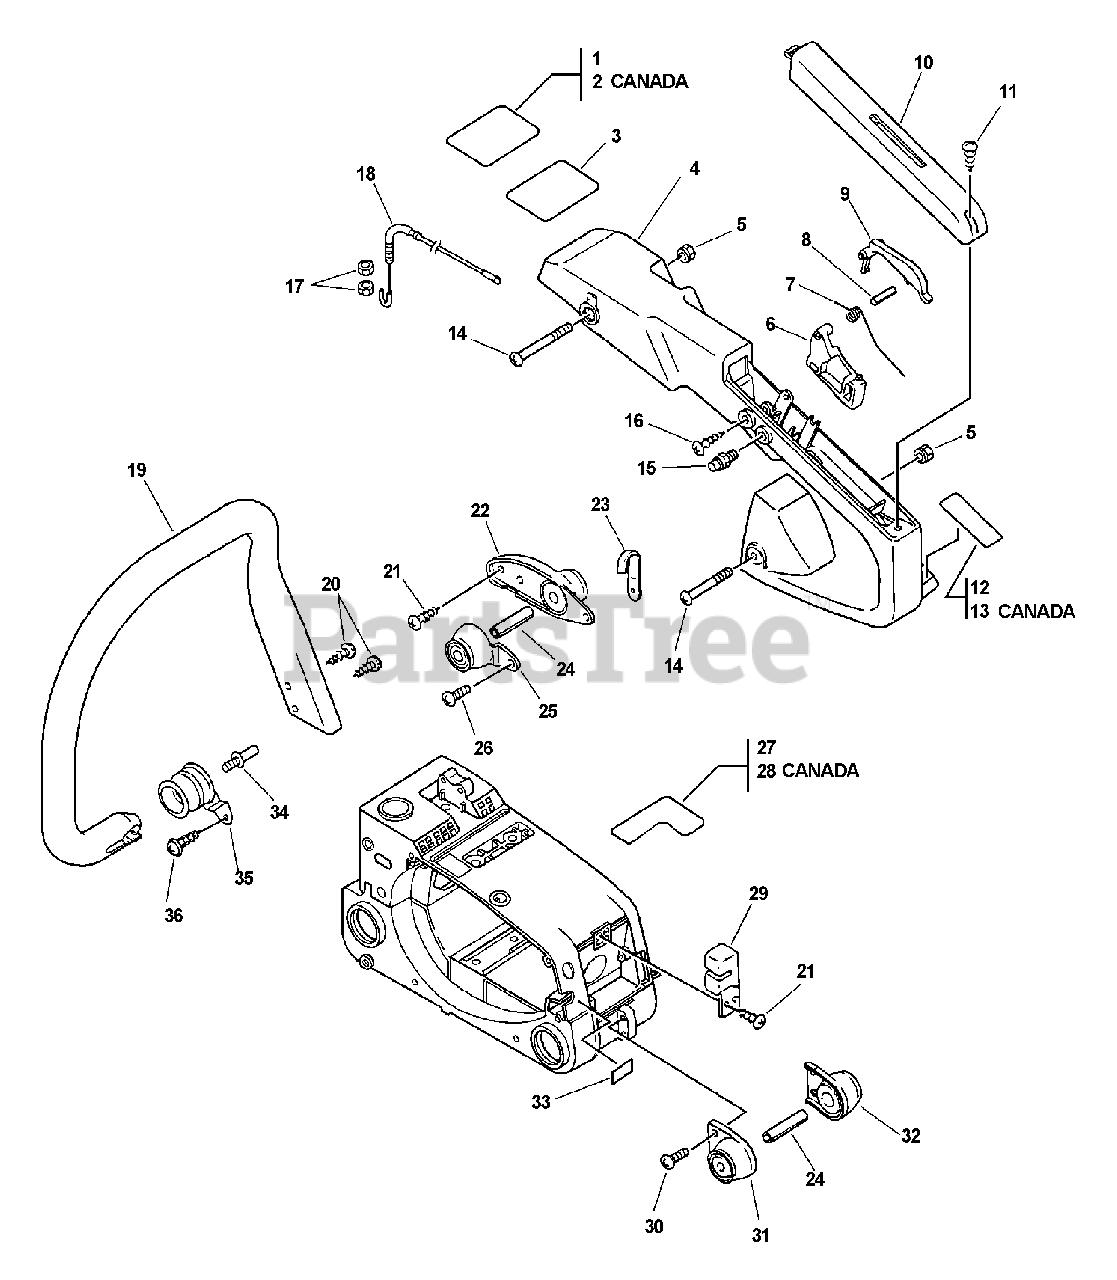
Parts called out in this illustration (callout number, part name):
1	LABEL, UL - KICK BACK
2	LABEL, CAUTION
3	LABEL, NOISE - ENGLISH/FRENCH
4	HANDLE, REAR
5	NUT, FLANGE M5
6	CONTROL, THROTTLE
7	SPRING, THROTTLE LOCKOUT
8	ROLLER, 4×19.8
9	LOCKOUT, THROTTLE
10	COVER, HANDLE
11	SCREW 4×22
12	LABEL, CAUTION
13	LABEL, ATTENTION - CANADA
14	SCREW 5×57
15	LOCK, THROTTLE TRIGGER
16	SCREW 4×25
18	CABLE, THROTTLE
19	HANDLE, FRONT
20	SCREW, TAPPING 5×20
21	SCREW 4×14
22	CUSHION
24	COLLAR 5
26	SCREW 4×10
27	LABEL, KICK BACK WARNING
28	LABEL - WARNING
30	SCREW 4×14
33	LABEL, STOP
35	CUSHION 5
36	SCREW 4×16
